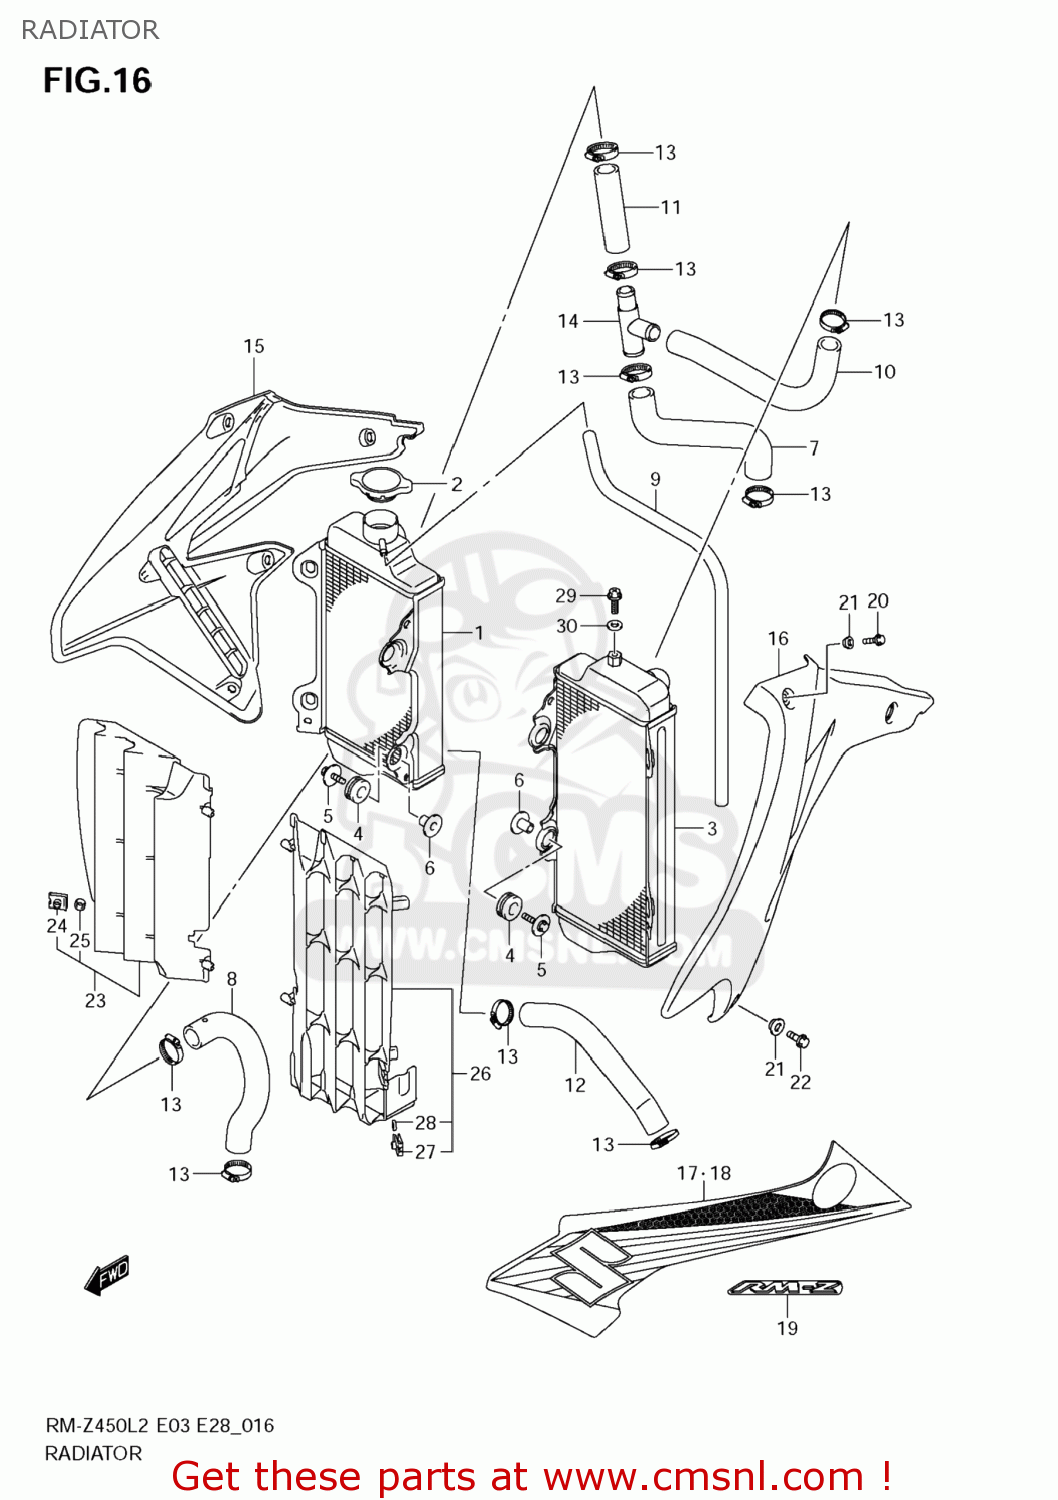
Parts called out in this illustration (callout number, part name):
1	RADIATOR,WATER,R
2	CAP COMP,RADIATOR
3	RADIATOR,WATER,L
4	CUSHION,RADIATOR LWR
5	BOLT(6X25)
6	SPACER(6.5X10.5X14.1)
7	HOSE,RADIATOR INLET
8	HOSE,RADIATOR OUTLET
9	HOSE(5X8X1000)
10	HOSE,RADIATOR JOINT UPR NO.1
11	HOSE,RADIATOR JOINT UPR NO.2
12	HOSE,RADIATOR JOINT LWR
13	CLAMP
14	JOINT,RADIATOR HOSE
15	COVER,RADIATOR,R
16	COVER,RADIATOR,L
17	TAPE,RADIATOR COVER,R
18	TAPE,RADIATOR COVER,L
19	EMBLEM,RADIATOR COVER
20	BOLT(6X12)
21	WASHER,FR FENDER
22	BOLT
23	LOUVER,RADIATOR,R
24	NUT
25	SPACER(6.2X10X2.2)
26	LOUVER,RADIATOR,L
27	NUT
28	SPACER(6.2X10X2.2)
29	UNION BOLT,AIR VENT
30	GASKET(6.4X11.5X0.8) (NAS)
